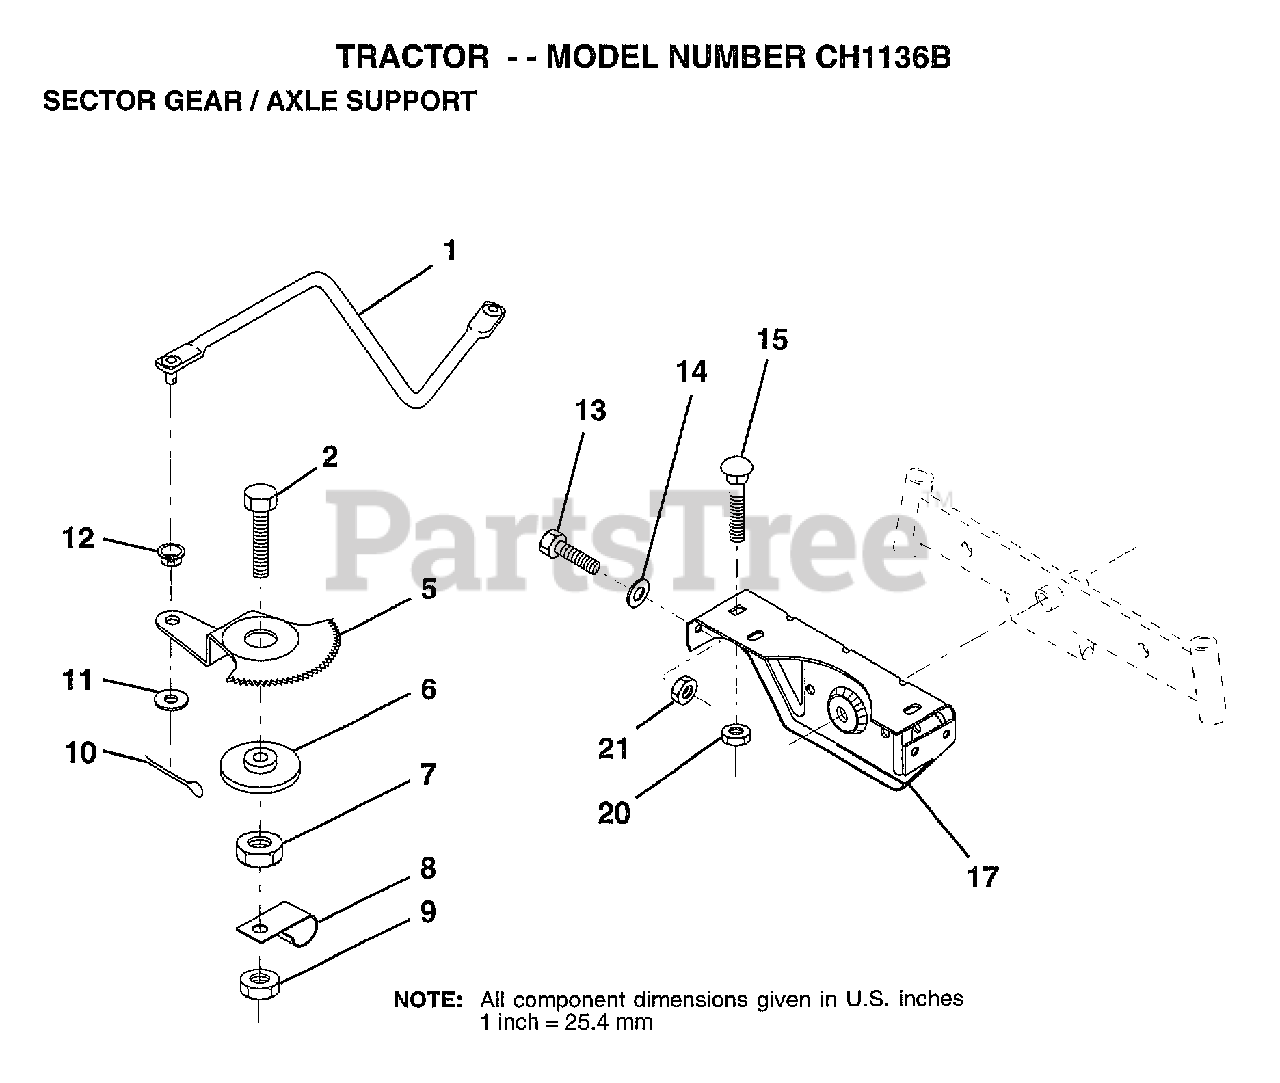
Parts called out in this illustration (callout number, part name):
1	DRAG LINK
2	"BOLT,HEX"
5	GEAR SECTOR
6	BUSHING
7	NUT
8	CLIP INSULATOR
9	NUT LTV
10	COTTER PIN
11	WASHER
12	BUSHING.DRAGLINK
13	BOLT
14	WASHER
15	BOLT
17	SUPT AXLE FRONT
